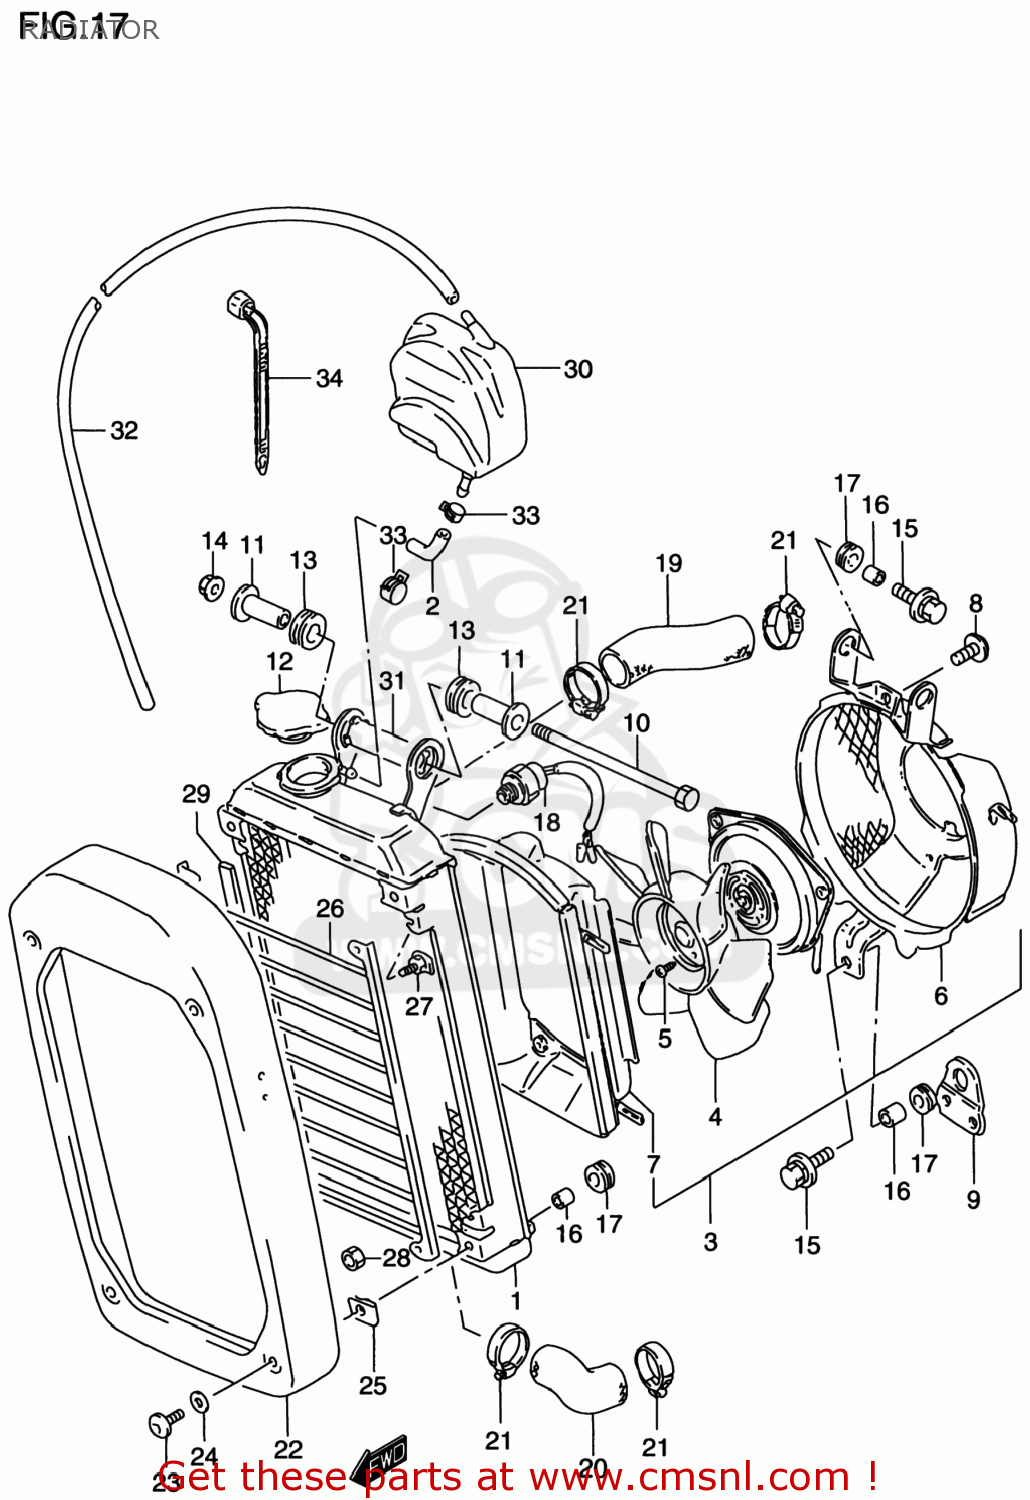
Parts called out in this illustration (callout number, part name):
1	RADIATOR ASSY,WATER
2	CAP,RADIATOR
3	FAN ASSY,RADIATOR
4	FAN
5	SCREW 4X6
6	SHROUD,FAN
7	DUCT,FAN
8	SCREW
9	BRACKET,RADIATOR FAN
10	BOLT(10X135)
11	SPACER,RADIATOR CUSHION NO.2
12	SPACER,RDTR CUSH NO.2 OUTER
13	CUSHION
14	NUT
15	BOLT
16	SPACER(6.5X9X8)
17	CUSHION
18	SWITCH,RADIATOR FAN
19	HOSE,RADIATOR INLET
20	HOSE,WATER PUMP OUTLET
21	CLAMP
22	COVER,RADIATOR
23	SCREW(6X10)
24	WASHER(6.5X14X2)
25	NUT
26	BUMPER,RADIATOR
27	BOLT
28	NUT
29	CUSHION,RADIATOR BUMPER
30	TANK,RESERVOIR
31	HOSE,RESERVE TANK INLET
32	HOSE,RESERVOIR TANK OUTLET
33	CLIP
34	CLAMP(L:125)
